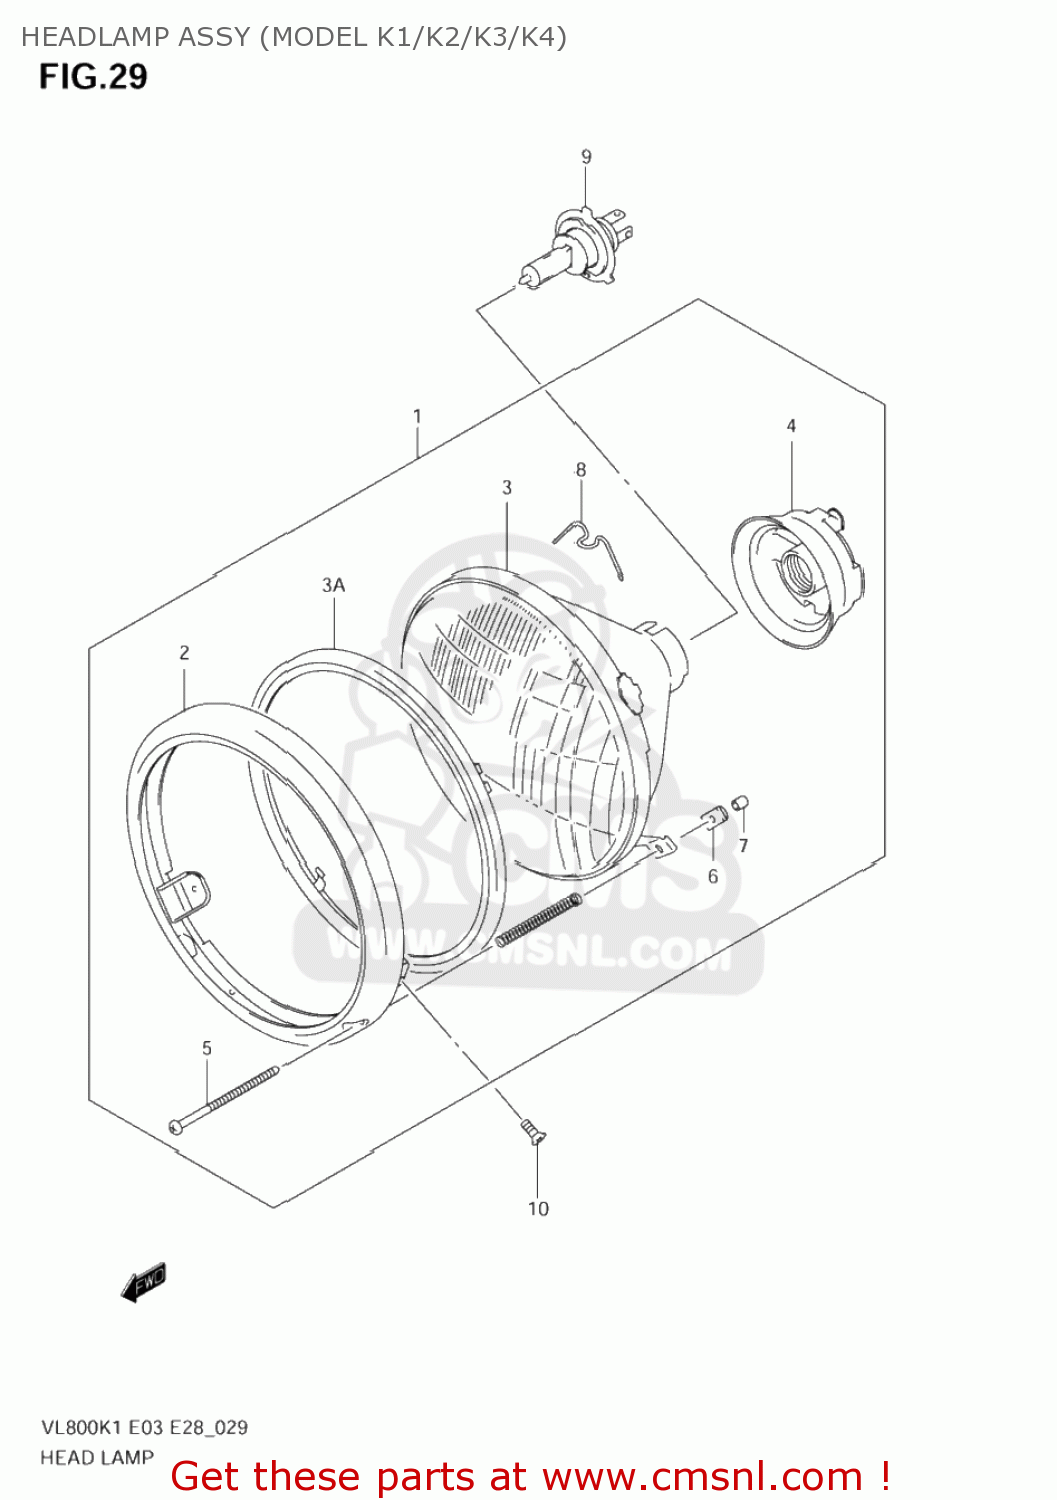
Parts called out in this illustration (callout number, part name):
1	HEADLAMP ASSY
2	RIM ASSY
3	LAMP UNIT
3A	RETAINING RING ASSY
4	COVER,SOCKET
5	SCREW
6	NUT
7	CAP,SCREW
8	SPRING
9	BULB(12V60/55W,H4)
10	SCREW(5X12)
